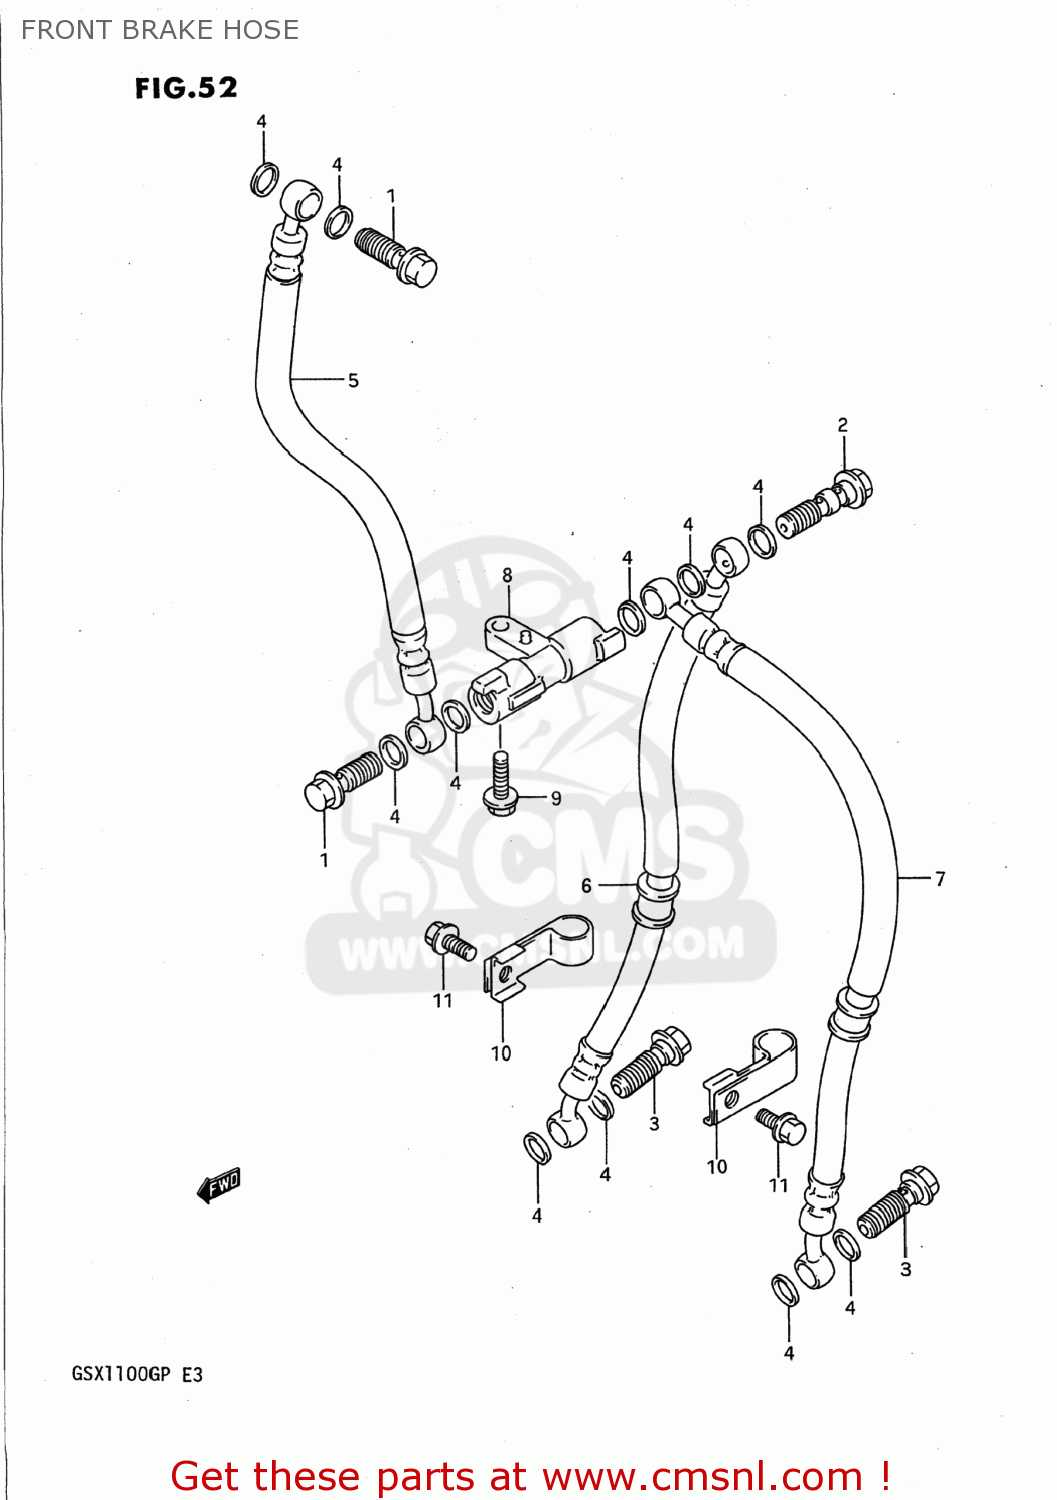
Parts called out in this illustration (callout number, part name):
1	BOLT UNION
2	BOLT UNION
3	BOLT 10X1.25X24
4	WASHER(10X15X1.5)
5	HOSE,FRONT BRAKE NO.1
6	HOSE COMP,FRONT BRAKE
7	HOSE COMP,FRONT BRAKE
8	JOINT,BRAKE HOSE
9	BOLT
10	CLAMP,FRONT BRAKE NO.2
11	BOLT 6X12
